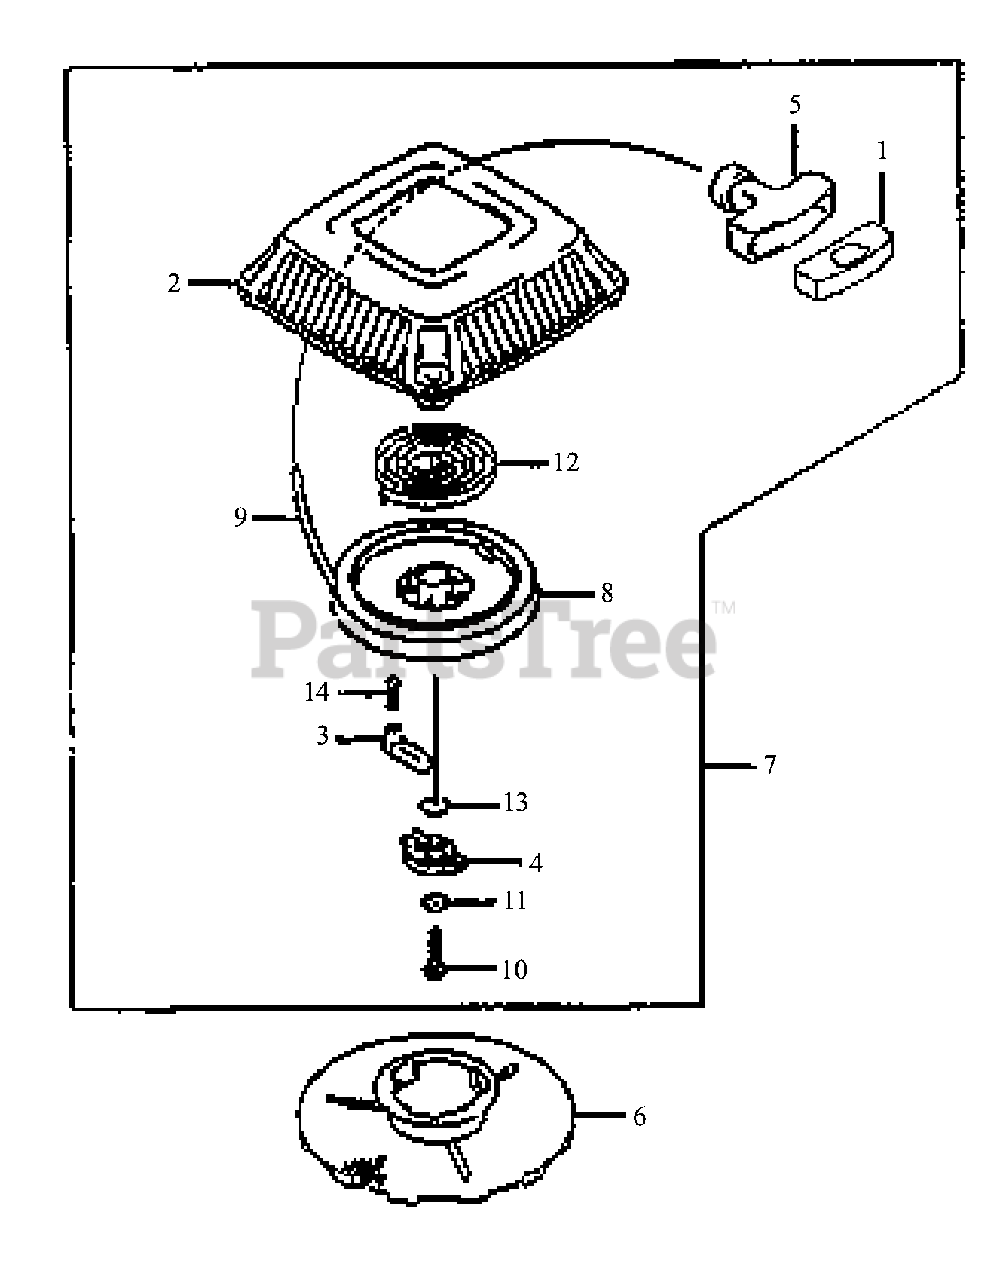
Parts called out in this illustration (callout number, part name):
2	Holder
3	Pawl, Recoil Starter
4	Retainer, Spring
5	Grip, Recoil Starter
6	Pulley, Starting
7	Starter, Recoil
8	Reel, Recoil Starter
9	Rope, 3.8x2450
11	Washer 5x12.8x1.2
12	Spring, Recoil
14	Spring, Return
